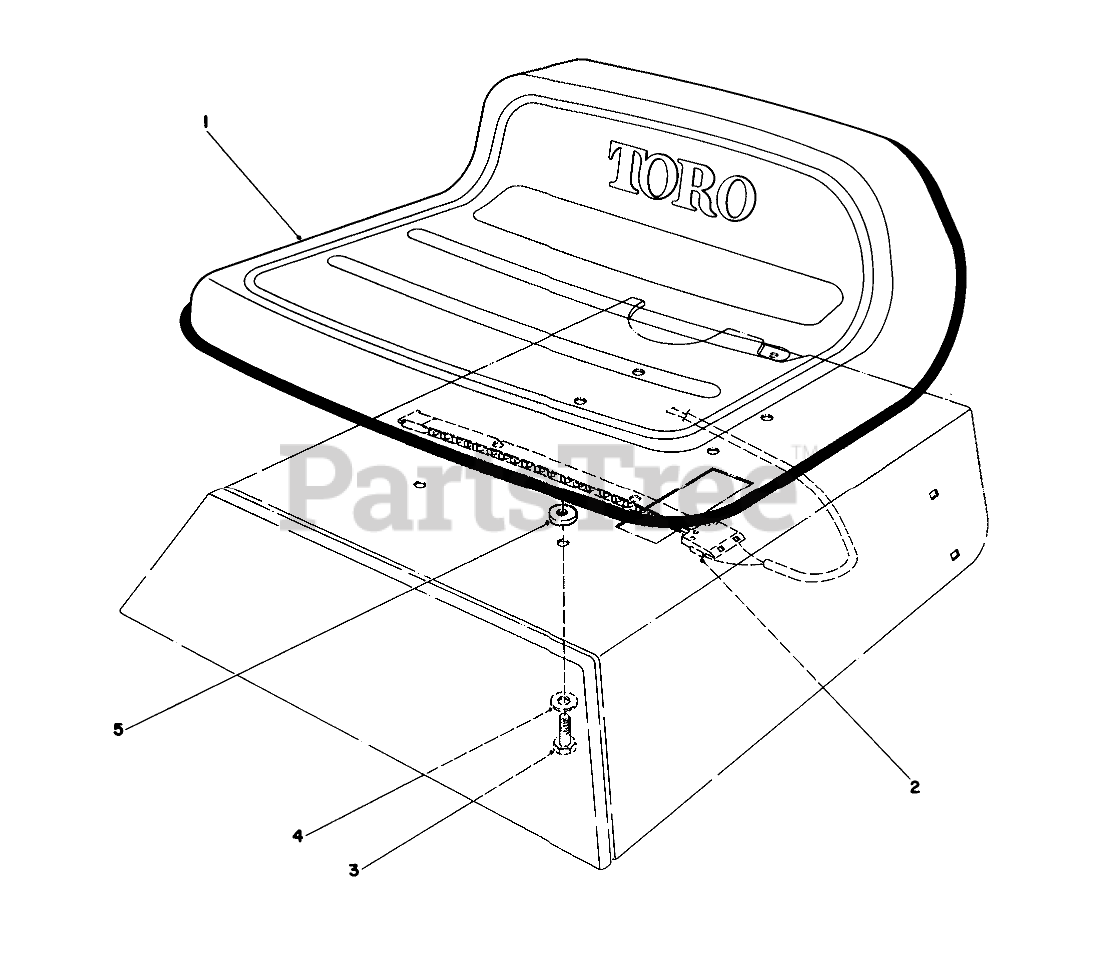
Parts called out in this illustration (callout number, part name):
1	Seat
2	SWITCH-SEAT
3	SCREW-HH
4	WASHER-FLAT
5	SPACER-PIN, MOUNTING
